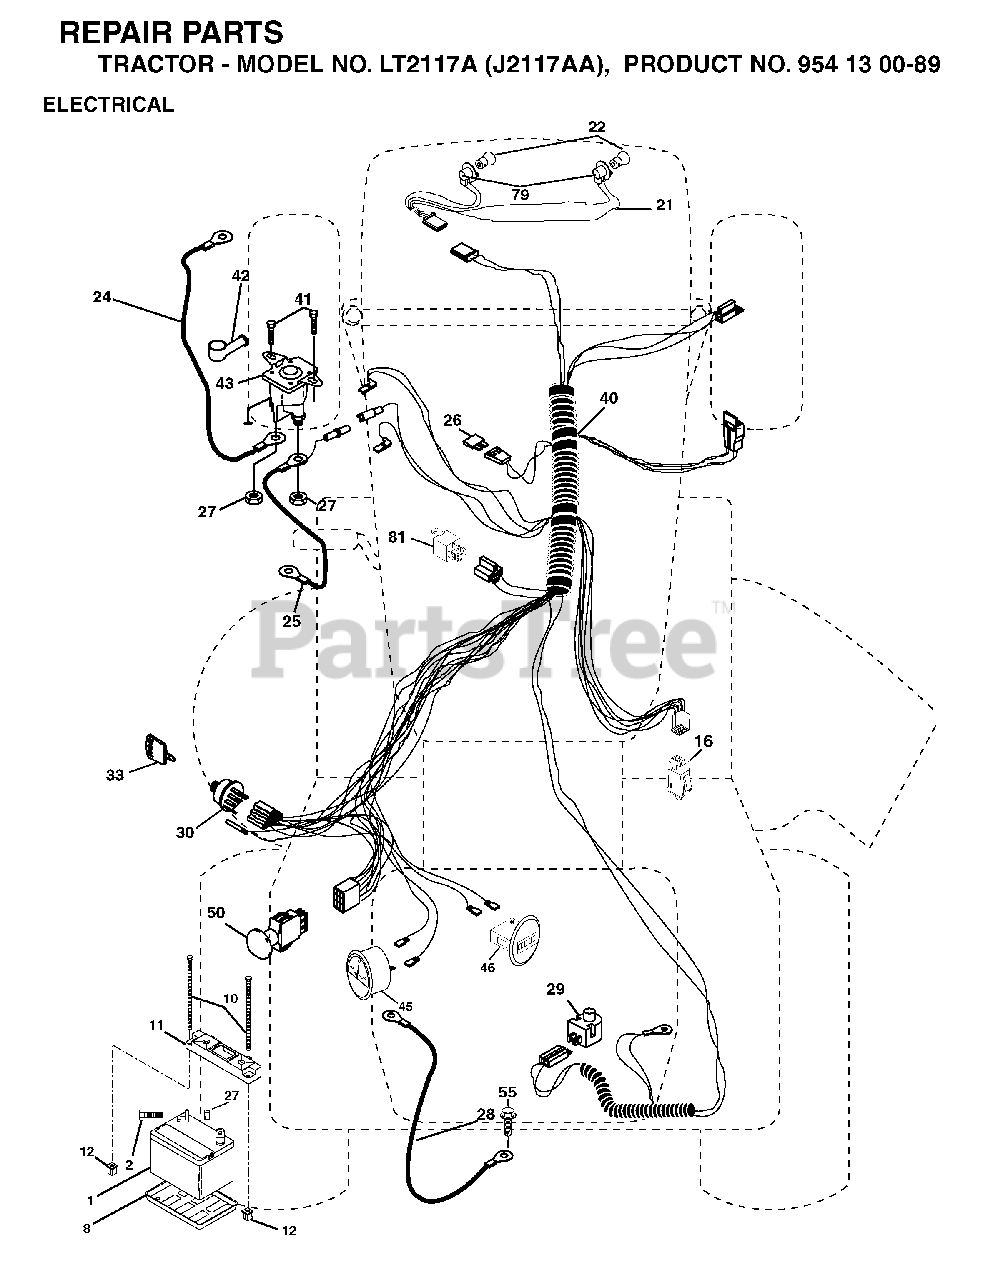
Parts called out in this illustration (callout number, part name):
1	REPL BY 532 12 38-99
8	BATTERY TRAY T
10	BOLT 1/4-20 X 7.5
11	BATTERY HOLDDOWN
12	NUT, PUSH NYLON 1/4" BATTERY
16	SWITCH INTERLOOK PUSH-IN
21	HARNESS.W/LIGHT SOCKET
22	LIGHTBULB
25	CABLE BATTERY 6 GA 22" W/16W
26	FUSE 20AMP
27	NUT
28	CABLE GROUND 6 GA 21" 90T BLK
29	PLUNGER SWITCH (COLOR:OLIVE)
30	IGNITION SWITCH
33	KEY MLD GEN DELTA
41	SCREW
42	TERMINAL COVER
43	SOLENOID
46	HOURMETER SNAP-IN
50	PTO SWITCH
79	BULB HOLDER ASM.
81	RELAY.ASSY.T
